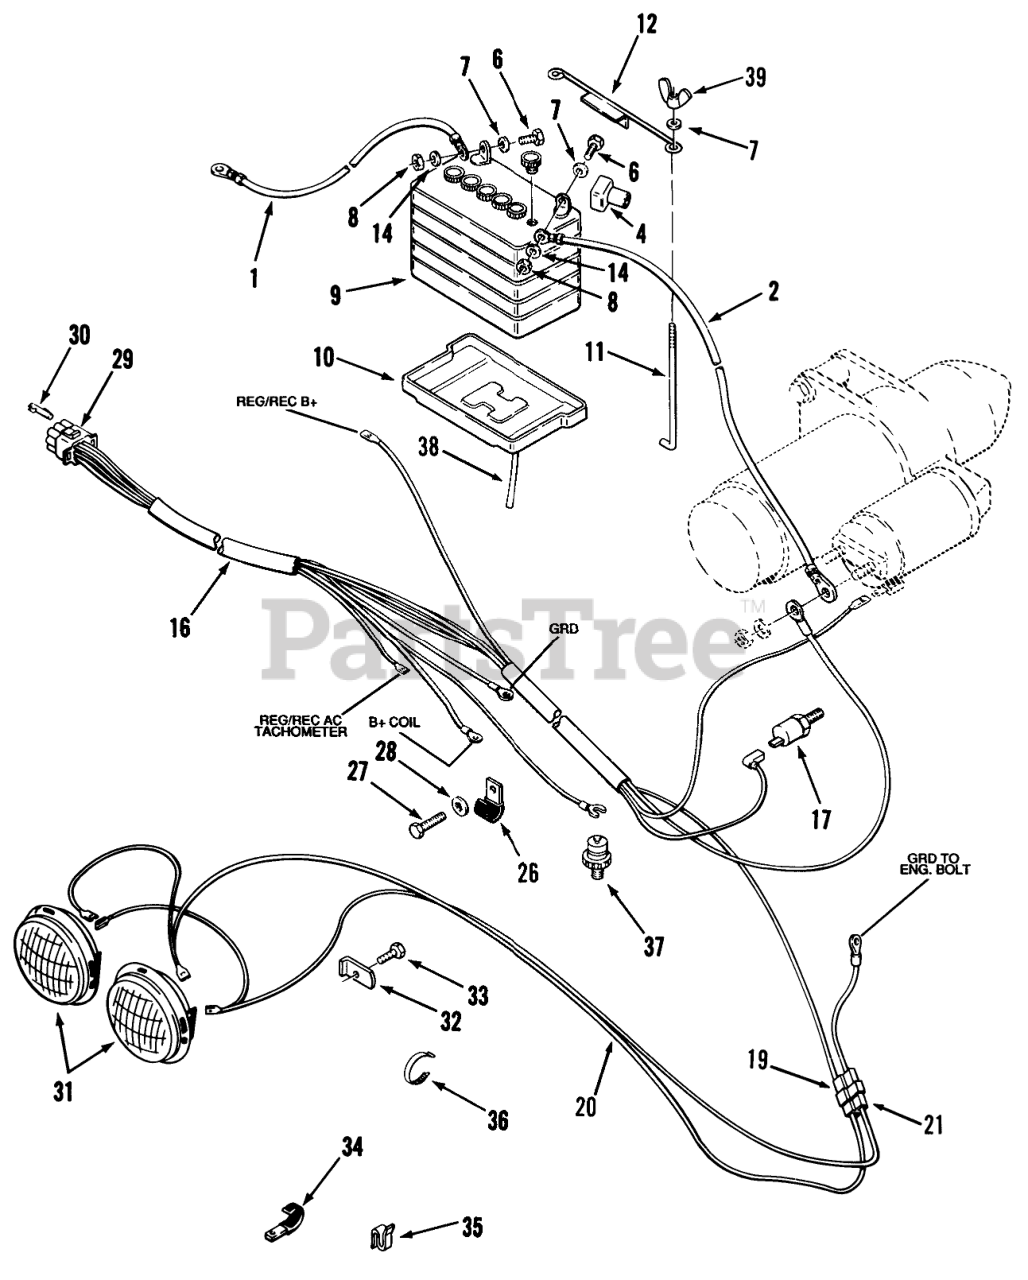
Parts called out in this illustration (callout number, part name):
1	ASS'Y-WIRE
2	ASS'Y-WIRE
4	Boot
6	Bolt
8	Nut
9	Battery
10	Bracket
10	THRUST WASHER
11	HOOK-BATTERY RETAIN
12	HOLDDOWN-BATTERY
14	Washer
16	WIRING HARNESS
17	HIGH TEMPERATURE
19	MALE CONNECTOR
20	HARNESS-HEADLIGHT
21	CONNECTOR BODY
26	Clip
27	Bolt
28	LOCKWASHER 1/4 IT
29	CONNECTOR CAP
30	CONTACT SOCKET
31	HEADLAMP
32	LOCK-HEADLIGHT
33	Bolt
34	CLIP
35	SPEED CLIP
36	PLASTIC TIE
37	LOW OIL PRESSURE
38	TUBE-BATTERY DRAIN
39	Nut
